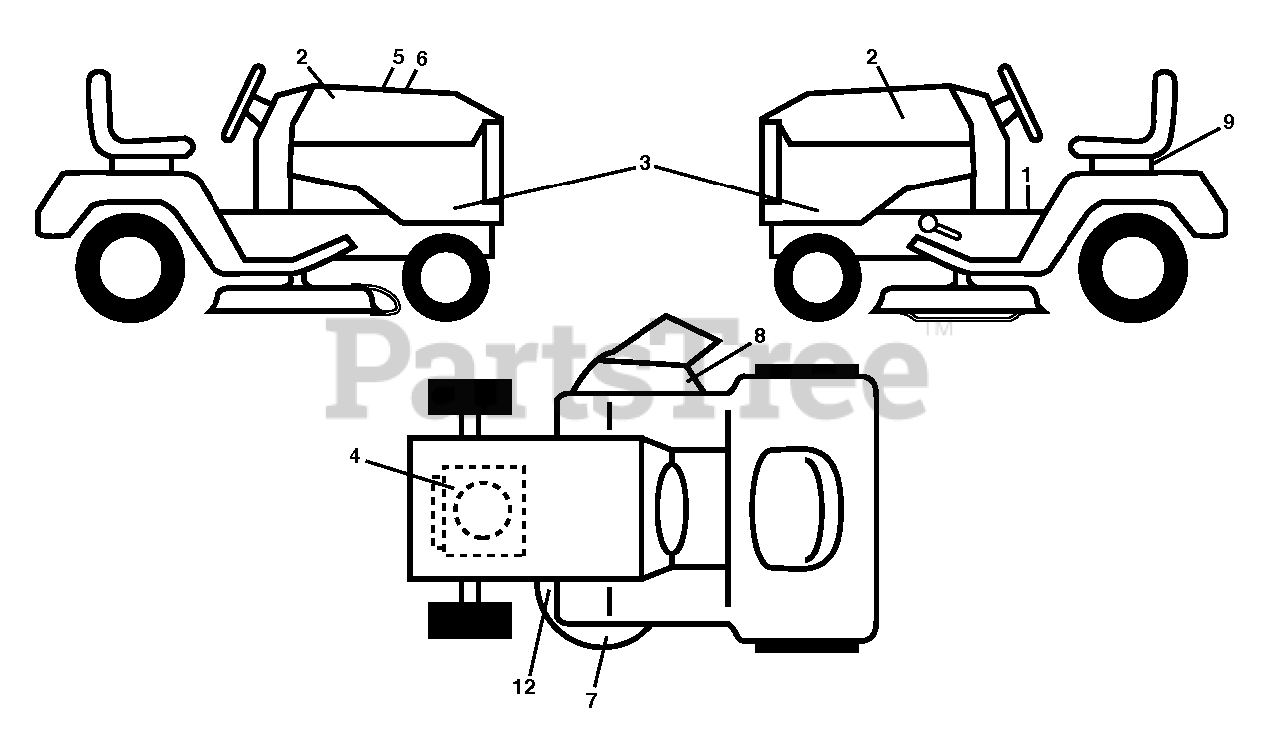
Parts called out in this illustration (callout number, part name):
1	DECAL.FENDER.WARNING.ENGLISH
2	DECAL.BADGE.170MM.TEXTLOGO.
3	DECAL.SDPNL.HGT2.YTH22V42.HUSQ
4	DECAL.ENG.BS.22INTK.DOM.381708
5	DECAL.WARNING.CUST.RESP.E85.
6	DECAL.RPL.BSM44.INTK.TLW.42
8	DECAL, DECK DEFLECTOR, WARNING
9	DECAL BTRY SYMBOLS
12	DECAL.V-BELT.SCH.42/46"MEC/ELE
